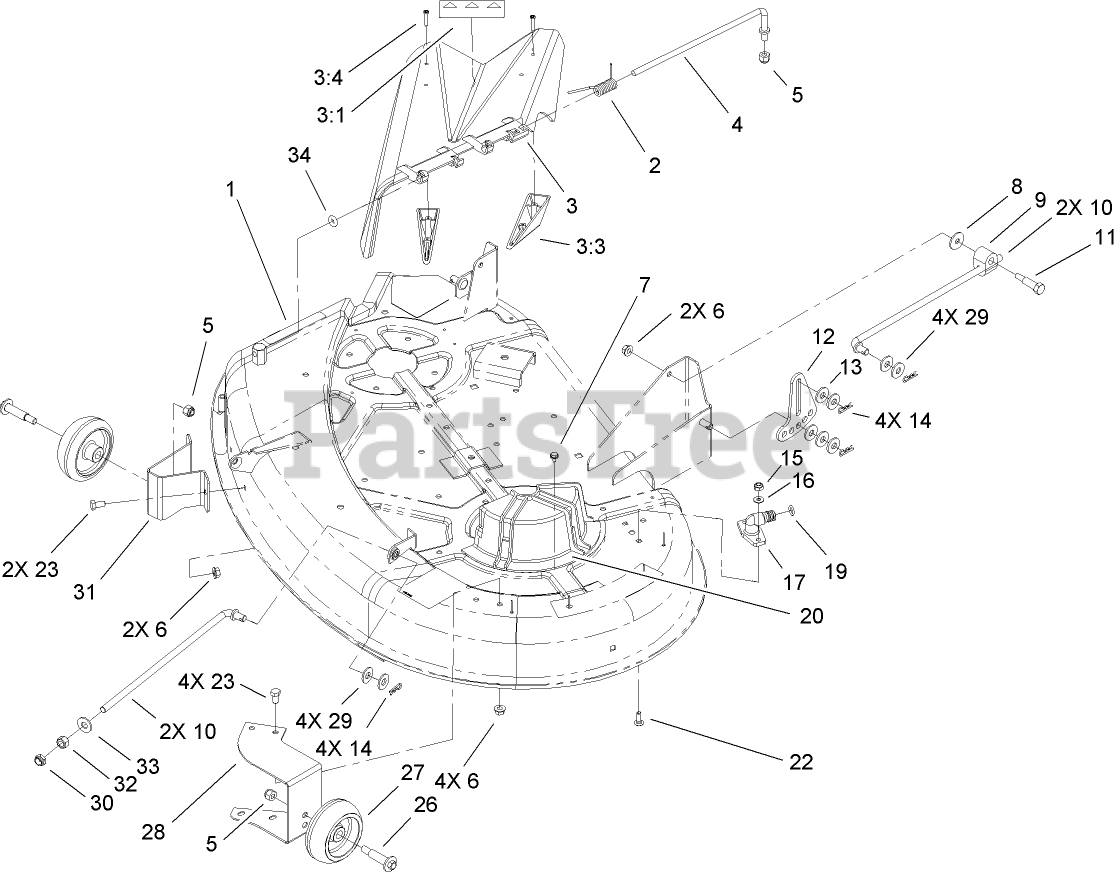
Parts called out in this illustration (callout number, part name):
1	38 INCH DECK ASM
2	SPRING
3	DEFLECTOR ASM
3:1	DECAL-DANGER
3:3	KICKER
3:4	SCREW-PPH
4	ROD-PIVOT
5	NUT-LOCK, NI
6	NUT-HF
7	SCREW-HWHTF
8	WASHER-PIVOT
9	TRUNNION-HOC
10	ROD-HANGER
11	SCREW-SHOULDER, HH
12	LINK-ADJUSTING, HOC
13	WASHER-HARDENED
14	PIN-HAIR
15	NUT-LOCK, NI
16	WASHER-FLAT
19	O-RING
20	GUIDE-BELT, LH
22	BOLT-CARR
23	SCREW-HH
26	SCREW-SHOULDER, HWH
27	WHEEL-GAGE
28	BRACKET-WHEEL, GAGE (FRONT, LH)
29	WASHER-FLAT
30	NUT-LOCK, NI
31	BRACKET-WHEEL, GAGE (FRONT, RH)
32	NUT-HEX
33	WASHER-FLAT
34	O-RING
